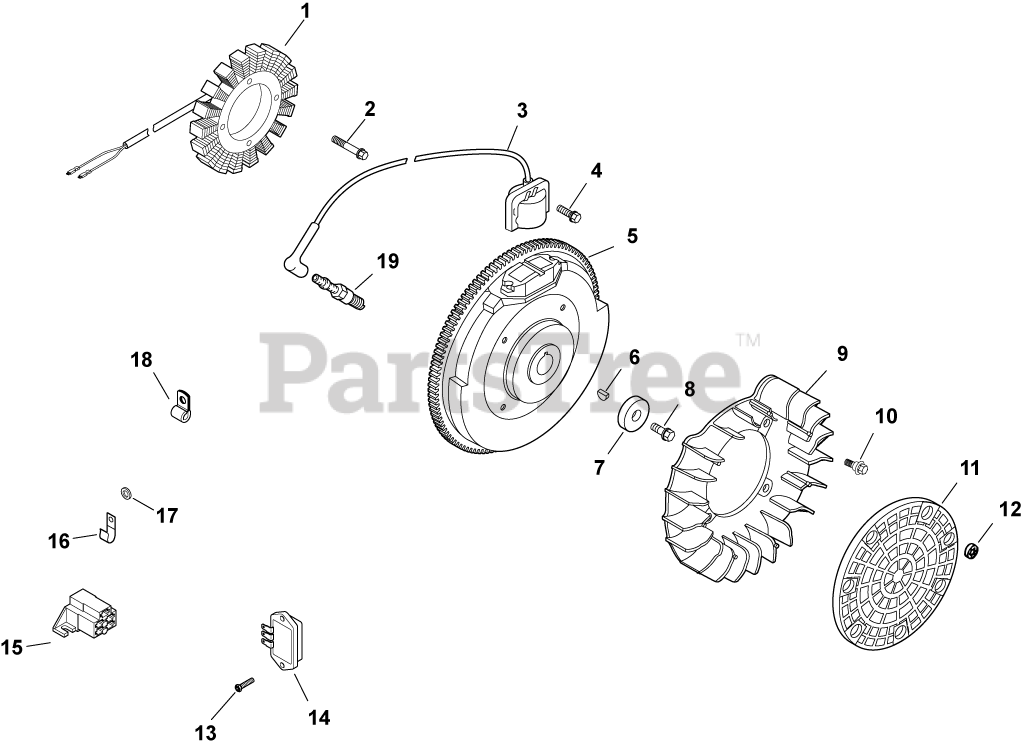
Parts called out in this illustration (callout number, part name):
1	KIT, 25 AMP STATOR ASSY.
2	SCREW, M5X0.8X25 - (#25086402S)
3	KIT, MODULE IGNTN (CDI FIXED)
4	SCREW, FLG THD FRM M5X.8X20-(#25086399S)
6	KEY, 3/16" X 5/8"
7	WASHER, FLAT 13/32"
8	SCREW, FLG M10X1.5X45 - (#25086361S)
9	FAN - USE (#24 157 11-S)
10	BOLT, SHOULDER
11	SCREEN, GRASS
13	SCREW, HEX FLANGE HI-LO
14	REG/RECTIFIER (20/25 AMP)-USE 25 403 20-
15	CONNECTOR
16	CLIP, CABLE
17	WASHER, FLAT 1/4" (O.D. 1/2")
19	PLUG, SPARK (STD)
